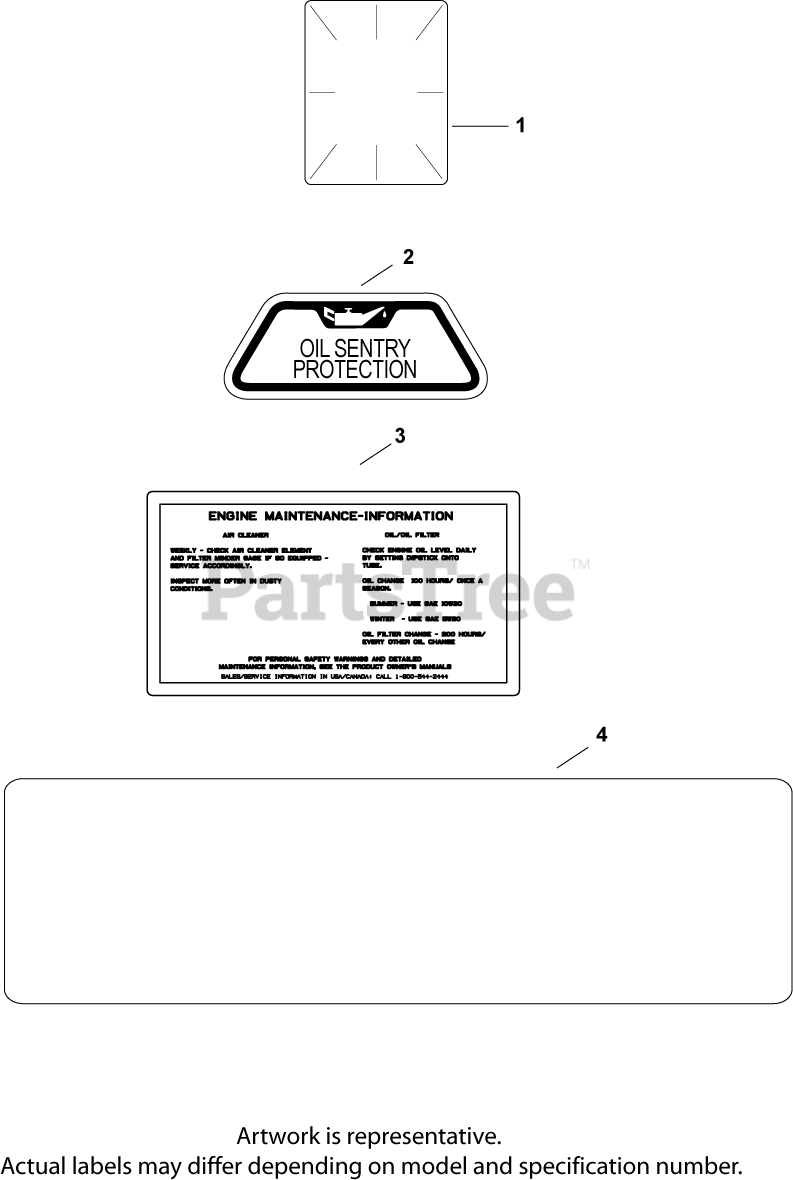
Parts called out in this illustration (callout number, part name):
1	DECAL, CLEAR LAMINATE USE 25 113 70-S
2	DECAL, OIL SENTRY - (#DSC)
3	DECAL, AIR CLEANER - (#DSC)
4	DECAL, 20 HP
